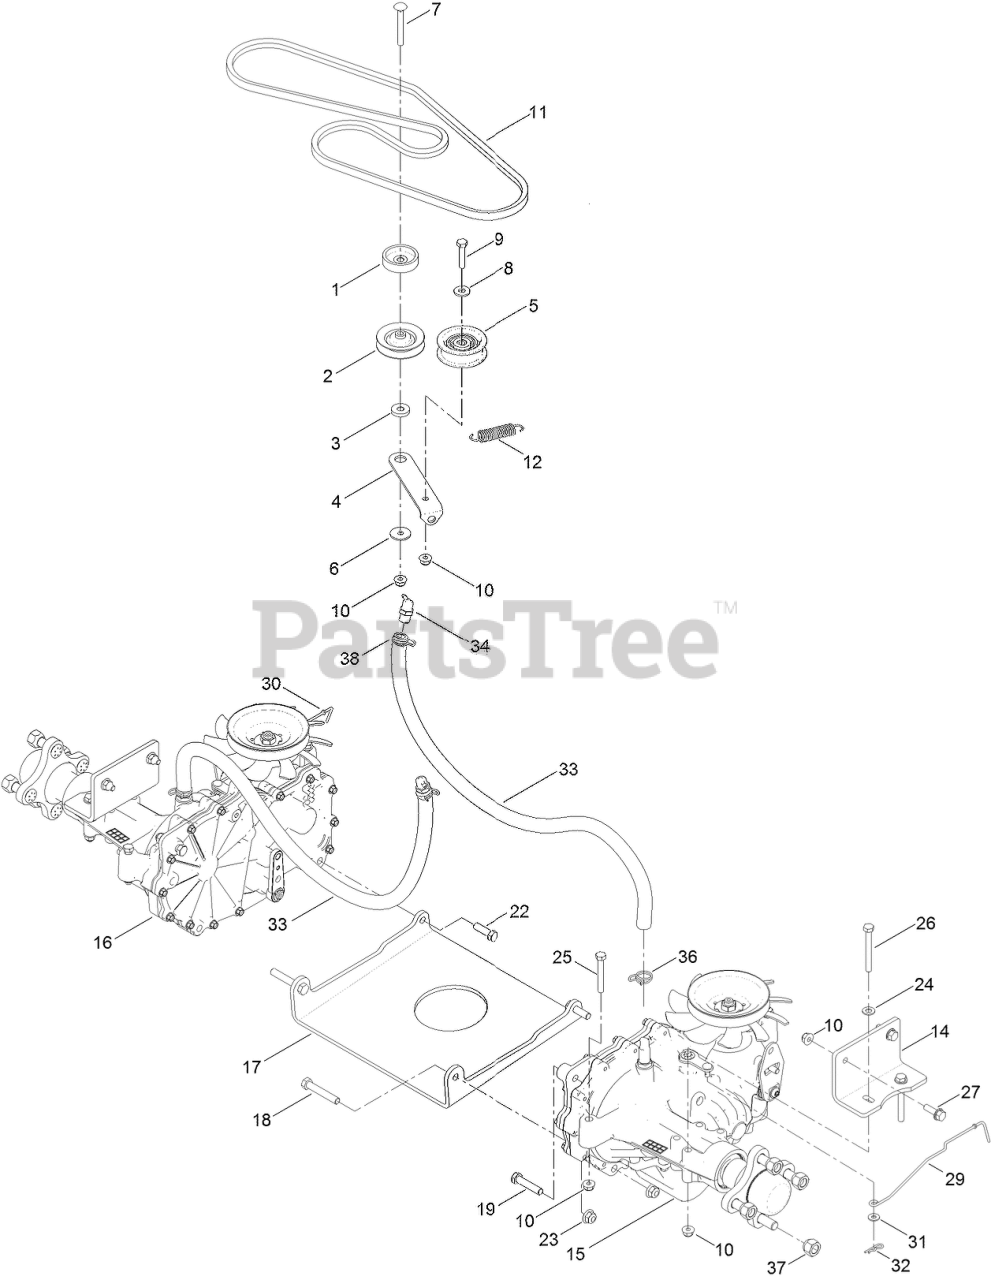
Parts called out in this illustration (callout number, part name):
1	SPACER
2	PULLEY-IDLER
3	SPACER-ARM, IDLER
4	ARM-IDLER
5	PULLEY-IDLER
6	WASHER-PIVOT
7	SCREW-CARR
8	WASHER-FLAT
9	SCREW-HH
10	NUT-HF, NI
11	V-BELT
12	SPRING-RETURN, PEDAL
14	MOUNT-HYDRO
15	LH HYDRO TRANSMISSION ASM
16	RH HYDRO TRANSMISSION ASM
17	PLATE-CROSS, HYDRO
18	SCREW-HH
19	SCREW-HH
22	SCREW-HH
23	NUT-HF, NI
24	WASHER-PLAIN
25	SCREW-HH
26	SCREW-HH
27	SCREW-HHF
29	ROD-BYPASS, LH
30	ROD-BYPASS, RH
31	WASHER
32	PIN-COTTER
33	HOSE-HYDRO
34	BREATHER KIT
36	CLAMP-HOSE
37	NUT-LUG
38	CLAMP-HOSE
